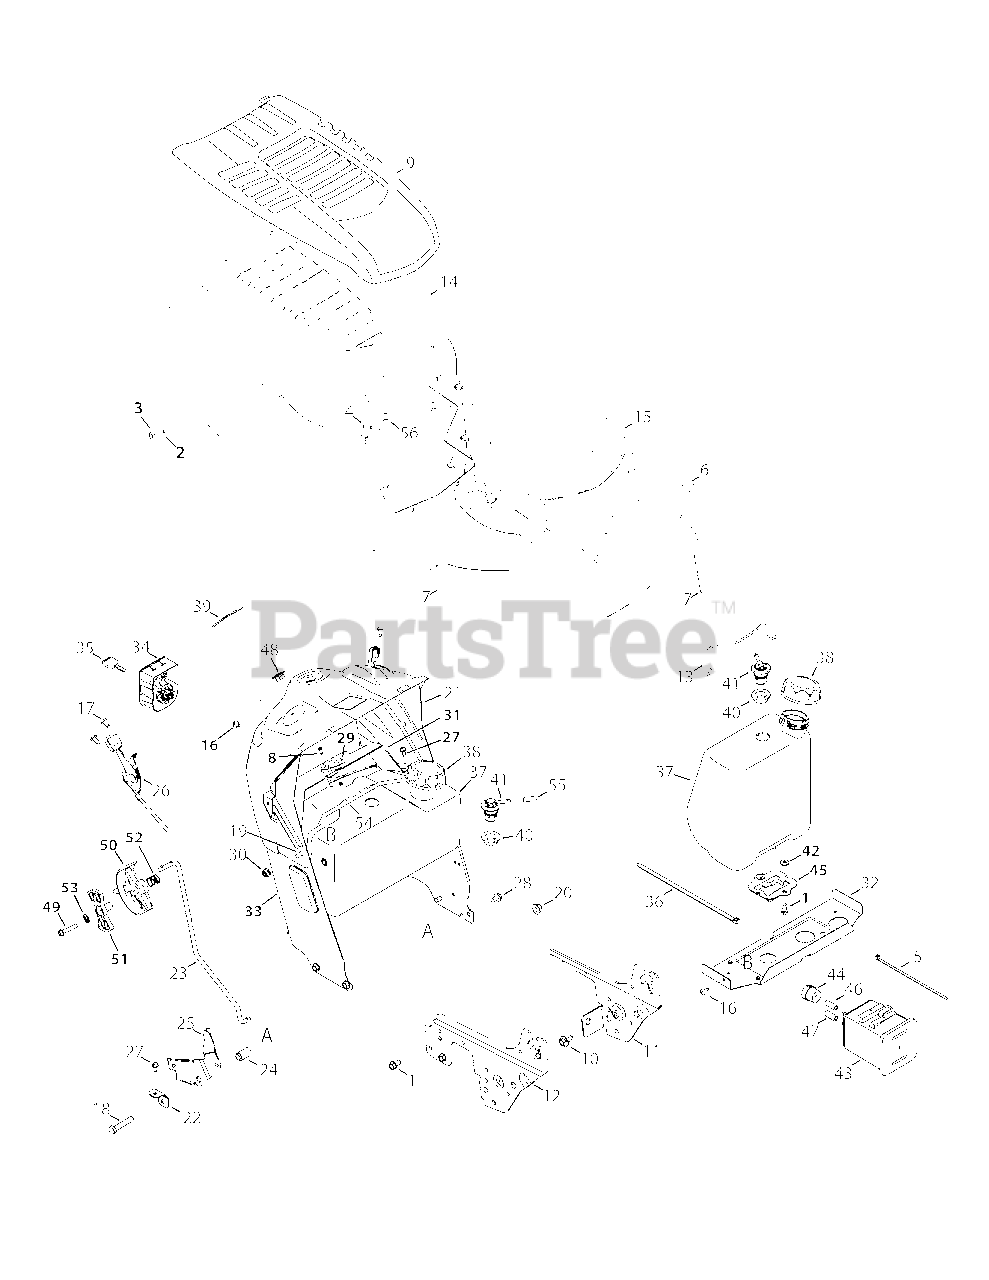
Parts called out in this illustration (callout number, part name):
1	Screw 5/16-18 x .750
2	Screw, #12-16 x 1.25
3	K-Style Bumper
4	Screw, 1/4 x .750
5	Cable Tie
6	Miniature lamp 12V socket
7	Grill Lens - LH
7	Grill Lens - RH
8	Screw, #10-16 x .500
9	Hood Scoop
10	Shoulder Screw .43 x .29
11	Suppport Bracket LH
12	Suppport Bracket RH
16	Screw, 1/4-20 x .500
17	Screw 1/4-20 x .500
18	Hex Screw 3/8-16 x 2.00
19	Hex Screw, 5/16-18 x .625
20	Flange Lock Nut 3/8-16
21	Dash, Upper
22	Speed Latch Tab
23	Speed Control Rod
24	Flange Spacer .39 x .671 x 1.095
25	Transmission Speed Latch
26	Throttle/Choke Control Cable
27	Tap Screw, 1/4-20, 0.625
28	Screw 5/16-18 x .625
29	Bearing, .628 ID x 1.36
30	Flange lock Nut 5/16-18
31	Bracket, Steering Support
32	Gas Tank Support Bracket
33	Dash, Lower NOWDO
34	Key Switch Module
35	Key, Assembly
36	Cable Tie
37	Fuel Tank, 1.36 Gallon, CARB
38	Fuel Cap, CARB
39	Ammeter Plug
40	Rubber Grommet
41	Rollover Valve
42	Washer, Flat, .344 x .750 x .120
43	Canister, Carbon, 5 Gallon
44	Filter, Vent, Canister
45	Bracket., Adapter, Canister
46	Hose, Fuel, Low Perm., White
47	Hose, Fuel, Low Perm., Yellow
48	Choke Plug
49	Hex Washer Screw, 1/4-20 x 1.50
50	Shift Lever
51	Index Control
52	Compr. Spring, .685 OD x .63
53	Lock Washer, 1/4
54	Fuel Tank Clamp Rod
55	Hose Vent, 3/16 EPA
56	Screw, 1/4-15 x 0.50
